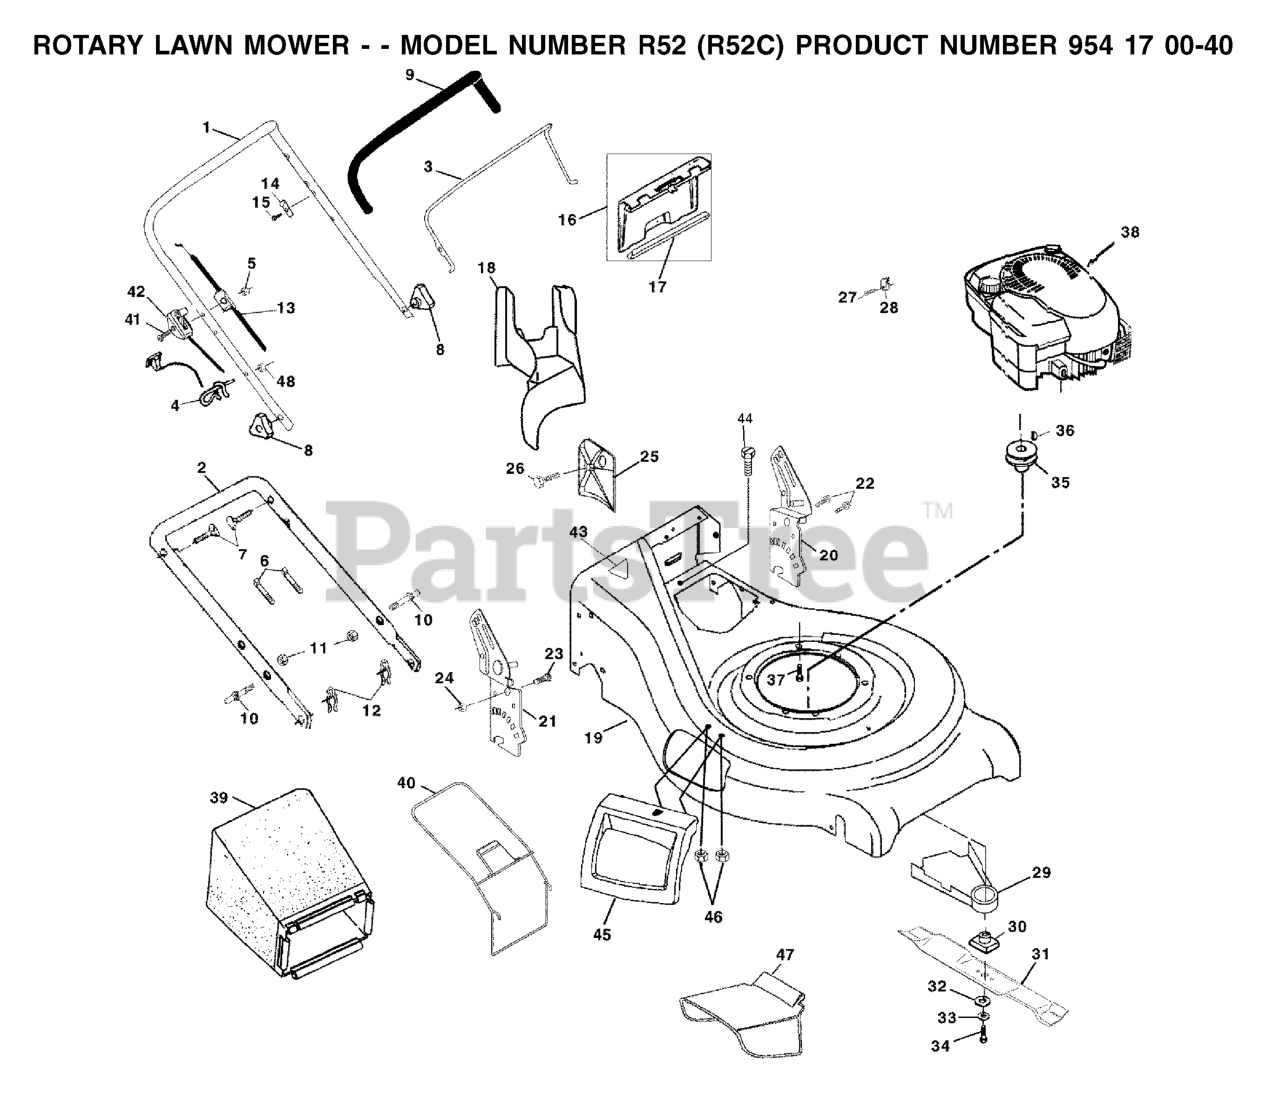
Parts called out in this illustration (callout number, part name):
1	HANDLE, UPPER DLX COMF. (GRIP)
2	HANDLE
3	CONTROL BAR
4	ROPE, GUIDE
5	NUT
6	TIE GUIDE
7	HANDLE BOLT
9	GRIP.HANDLE.FOAM
10	BOLT
11	NUT
12	HAIRPIN COTTER
13	ENGINE ZONE CONTROL
14	BRACKET UPSTOP
15	SCREW.HEX.HEAD.WASHER.10-16
16	KIT.DOOR.REAR.21.WRAPPED.BLACK
17	SEAL, DOOR
18	MULCHER PLUG
20	.RACKET
21	RIGHT HANDLE BRKT. ASSM.
22	SELF-TAPPING SCREW 5/16-18X3/4
23	BOLT, HEX HEAD 5/16-18
24	LOCKNUT
25	CLIPPING DEFLECTOR
27	SCREW.HEX.HEAD.WASHER.10-16
28	CABLE CLAMP(ENGINE)
29	SHIELD.DEBRIS.21.RWGD.EZ
30	BLADE ADAPTOR
32	WASHER,HARDEN
33	LOCKWASHER
34	SCREW, HEX HD 3/8-24 X 1-3/8
35	ENGINE.PULLEY.FWG
36	HI PRO KEY PM WSL
37	BOLT 3/8-16X1-1/8
40	FRAME.GRASS.CATCHER.21.RGD
41	SCREW 1/4-20 X 2.12
42	CONTRL.THROTTLE.
43	DECAL.INTERNATIONL.CUTFINGER
45	DOOR.ASM.MULCH.21.RWD
47	DEFLECTOR.21.MCUT.RWGD.GRAY
48	NUT
